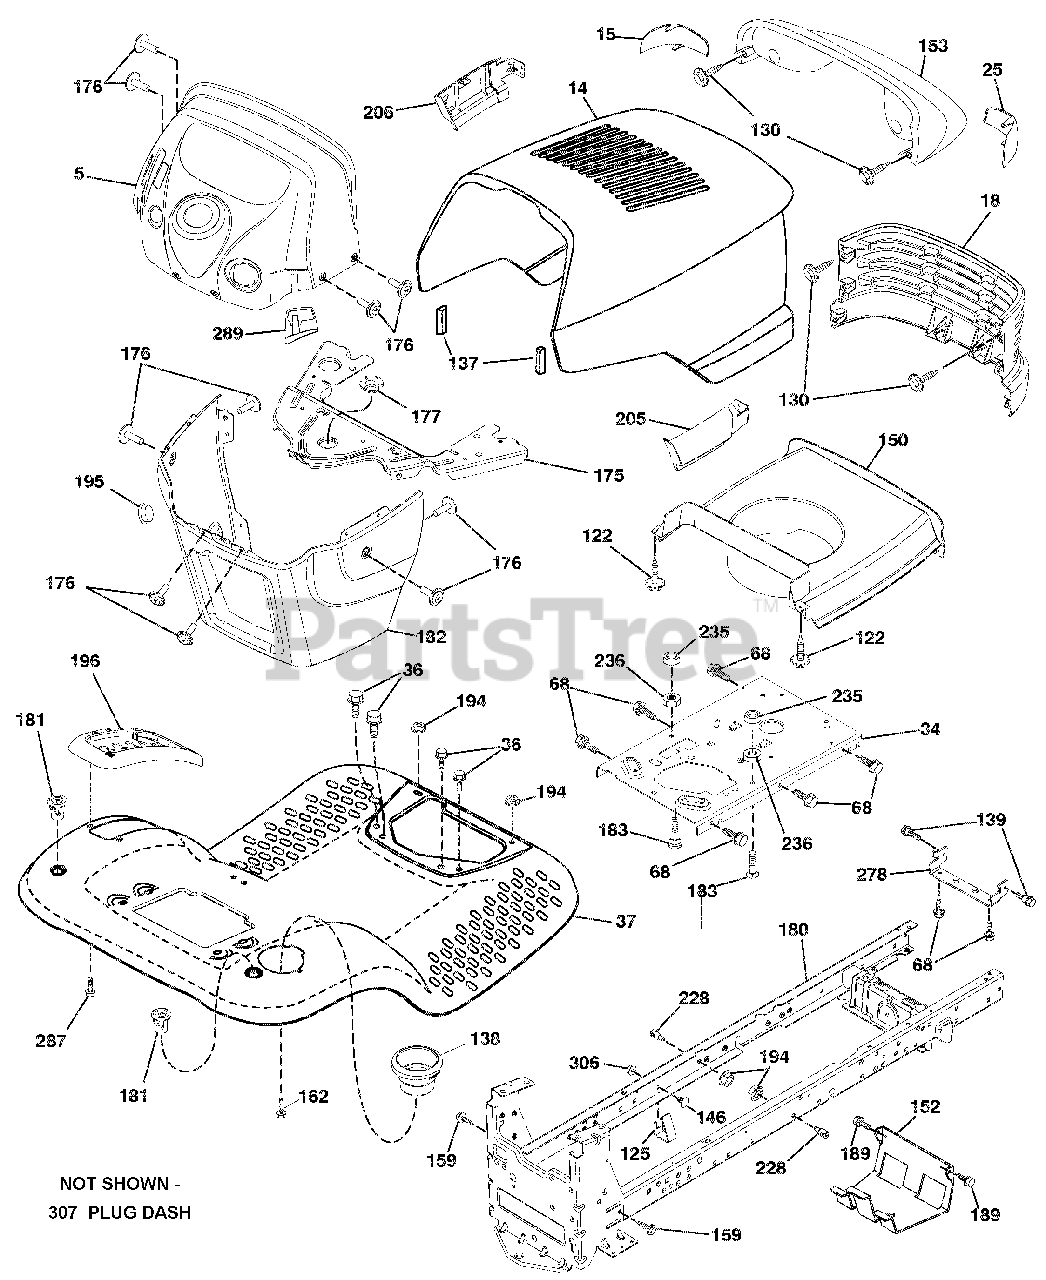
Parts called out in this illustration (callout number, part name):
5	DASH STEALTH ELE RECT 428 TEX
15	LENS ELITE ARIENS BLACK
18	GRILLE ELITE ARIENS BLACK
25	LENS ELITE HUSQ CLEAR RH
34	PLATE ENGINE WELDED CHASSIS
36	SCREW.5/16-18X3/4.SMGML.TAP/R
37	FENDER TLT W/CPH W/FW 422
68	SCREW.THDROL.5/16-18 X 1/2TYTT
122	SCREW TO 32 X 5/8
125	CLIP.FUEL.LINE
137	BUMPER HOOD LARGE 1.75
138	CUPHOLDER TL TEX 428
139	BOLT SHOULDER 5/16-18
150	AIR DUCT ENGINE ELITE SV
152	SHIELD.BROWNING.W/TEX
153	ASM LIGHT BOX
159	SCREW.HEXWSH THDR3/8-16X3/4.BL
162	SCREW.HEX.WSH.HI-LO.1/4X1/2UNC
175	CROSSMEMBER LT
176	SCREW.#10-24X5/8.RND.QUDRX.GIM
177	BUSHING.STEERING.YT/GT
180	CHASS WLDMT TL 12 GA/2PC 18/22
181	BUSHING MNT FEND CRGO BLK TEX
182	DASH TOWER LT CCS
183	BOLT.FIN.HEX.5/16-18 UNC X1-1/
189	SCREW.5/16-18X3/4.SMGML.TAP/BL
194	Nut, Lock Hex Flange 5/16-18 u
195	PLUG HOLE DASH TOWER
196	CONSOLE ASSEMBLY
205	SKIRT SIDE RH ELITE HUSQ 428
206	SKIRT SIDE LH ELITE 428
228	STUD.FASTNER.W/'D'ANTI-ROTATIO
235	SPACER.FENDER
236	NUT.CENTER LOCK.5/16-18 UNC
278	X-PIECE HOOD
287	SCREW.HEX.WASHEAD.1/4-20 X 3/8
289	PLUG CRUISE CONTORL
306	Nut, Hex, Flangelock 3/8-16
307	PLUG DASH
